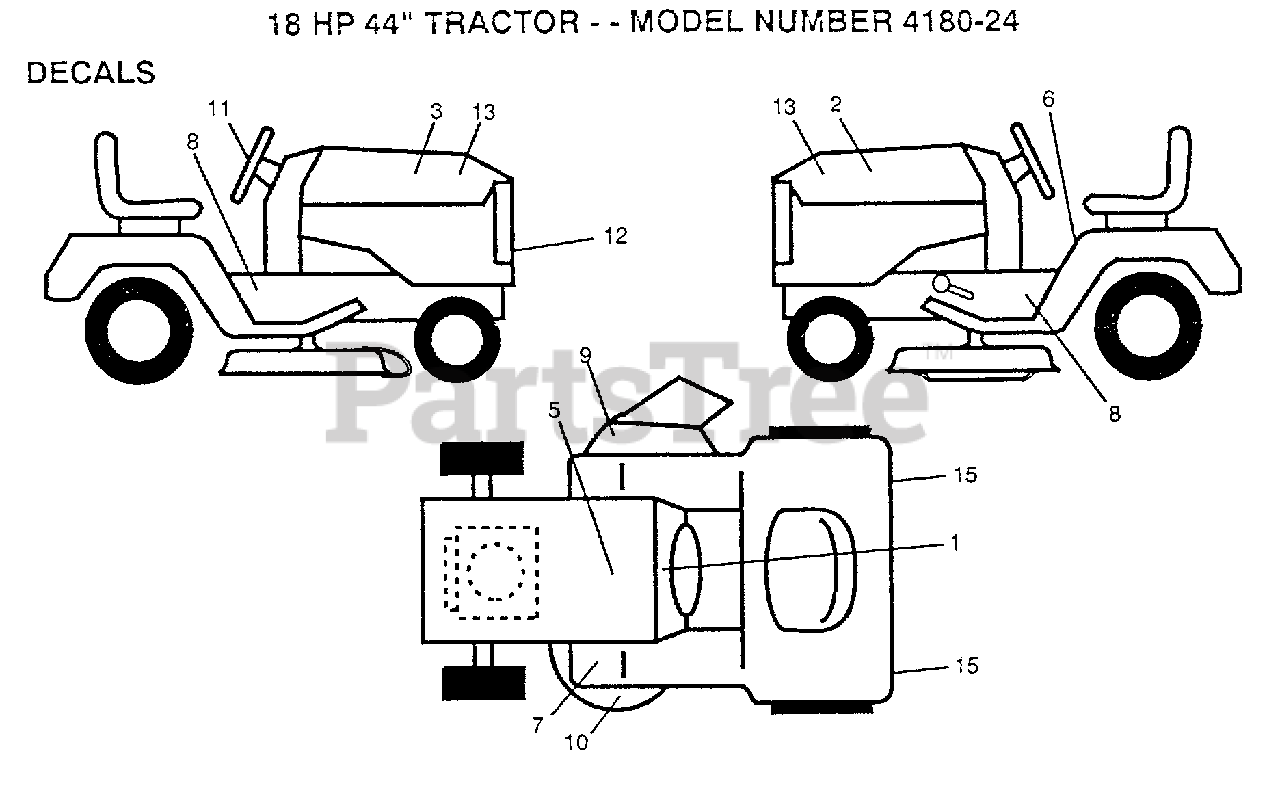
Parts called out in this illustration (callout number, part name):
2	HOOD DECAL LH
4	REFLECTOR-TAIL YT
5	DECAL
6	DECAL CAUTION
7	DECAL T
9	DECAL WARNING
10	DECAL-INST YT
12	GRILL DECAL
13	NAMEPLATE LOGO
